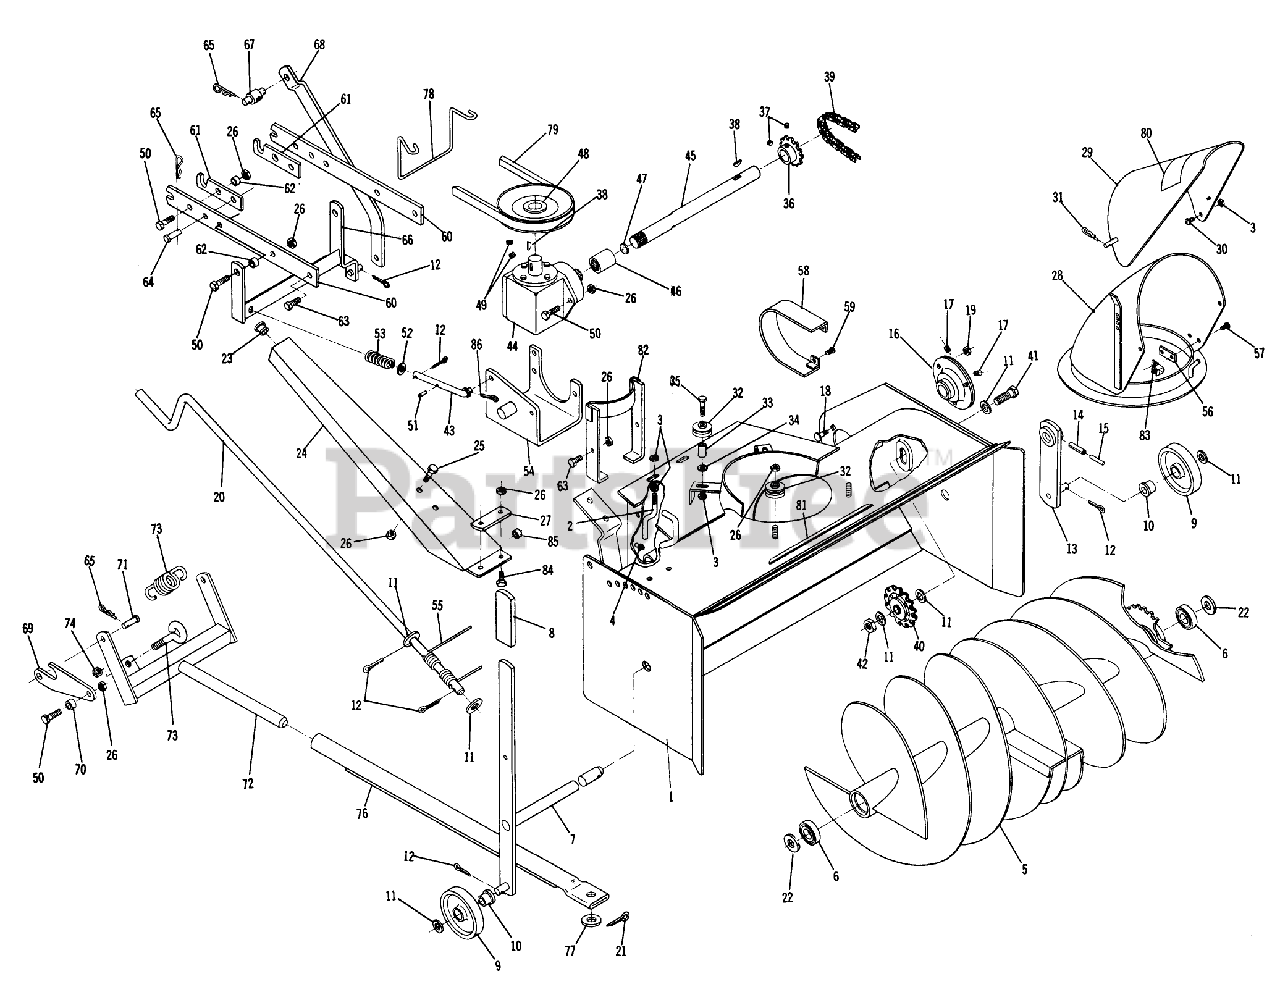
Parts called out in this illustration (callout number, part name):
1	Wrapper Assembly
2	Stud-Belt Guide
3	Nut-Nylok
4	Fitting
6	BEARING-BALL
8	Grip
11	Washer
12	Cotter Pin
14	ROLL PIN 1/4 X 1-1/4
15	PIN-SPIROL
17	Set Screw-Nylok 5/16-18 x 5/16
18	Bolt Hex 5/16-18 x 3/4
19	Nut-Nylok
21	Cotter Pin 3/16 x 1
22	Washer
23	NYLINER BUSHING
24	Support-Crank
25	Bolt Hex 3/8-16 x 5/8
30	Bolt Pan Head 1/4-20 x 1/2
31	Hairpin
34	Washer
35	Bolt 1/4 20 x 1 1/4
37	Set Screw Nylok
38	Key
39	Chain
41	Bolt-1/2-13-1 3/4
42	Locknut-1/2-13
43	Connecting Rod
44	Gear Box-Complete
45	ORDER FROM PEERLESS
46	Coupling
47	Felt Disc
48	Pulley "B" Section
49	Set Screw 5/16-18 x 1/4
50	Bolt 3/8-16 x 1
51	Spirol Pin 1/8 x 1
52	Washer
53	Spring
54	Gear Box Support
57	Screw #10-16 x 1/2 Pan Head
62	SPACER
63	Bolt 3/8-16 x 1
64	Clevis Pin
65	Hairpin
66	Hanger
70	SPACER CLUTCH ARM
71	Clevis Pin 3/8 x 3/4
73	EYEBOLT
74	3/8-16 E.S.
77	Washer, 5/8
78	Guide-Belt
80	Decal-Caution
82	Belt Guide
83	CLAMP
85	Bushing
86	Hairpin
